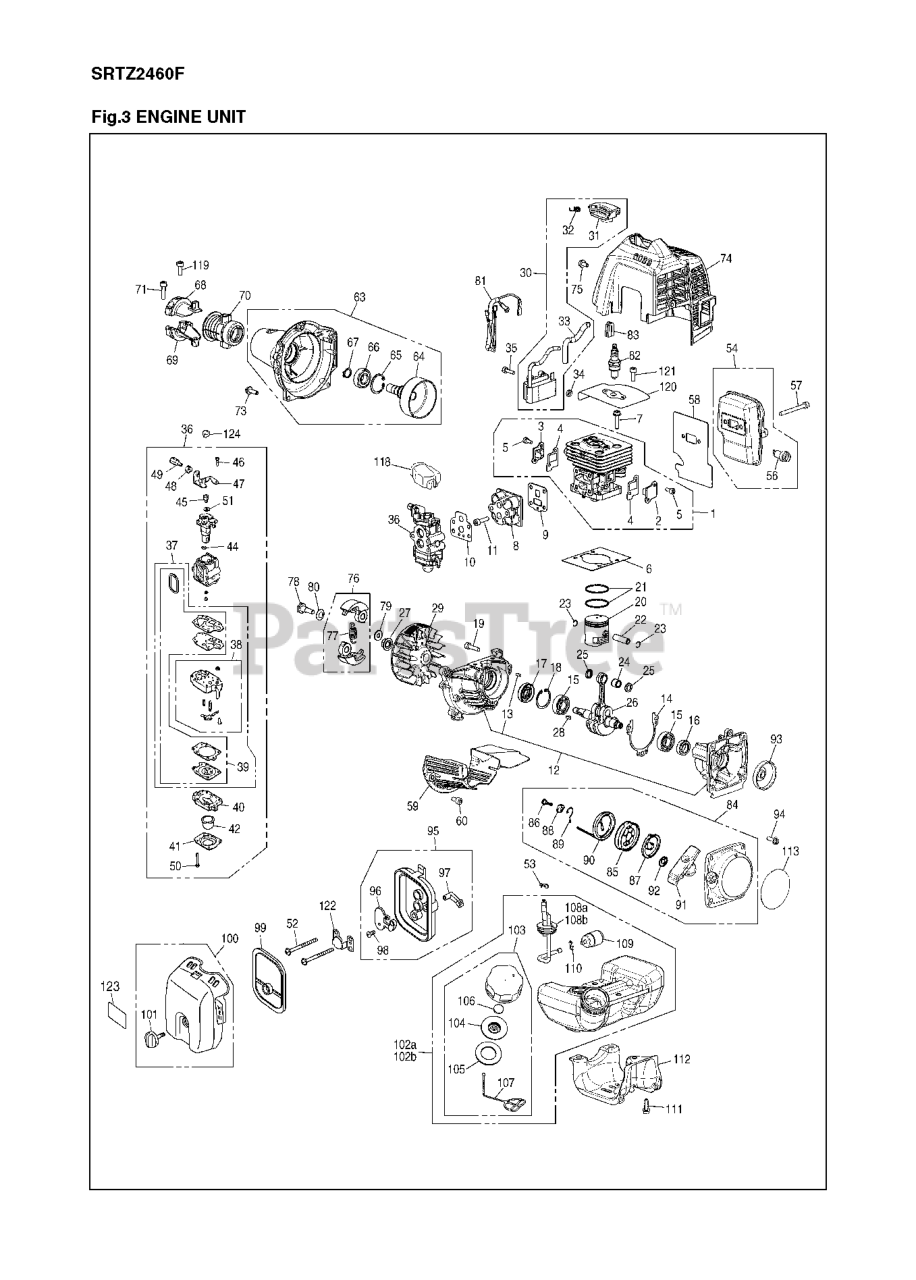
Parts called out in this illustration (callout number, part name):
1	CYLINDER COMP
2	COVER, TR-S
3	COVER, TR-F
4	GASKET, TR
5	BOLT
6	GASKET, BASE
7	BOLT
8	INSULATOR
9	INSULATOR GASKET(R-848F0814B0)
10	GASKET, CARB
11	BOLT TORX
12	CRANKCASE-C
13	PIN
14	GASKET, CASE
17	SEAL
22	PIN
26	CRANKSHAFT-C
27	NUT
28	KEY
30	COIL ASSY
34	SPACER
36	CARBURETOR ASSY
37	REBUILD KIT
38	CARBURETOR BODY
39	GASKET KIT
41	1OVER
44	RING
45	SWIVEL
46	SCREW
47	BRACKET
49	ADJUSTER
51	WASHER
52	BOLT TORX
53	CLIP
56	ARRESTER
58	GASKET, MUFFLER
63	COVER, C
64	DRUM (RPLS 481031120-22)
68	BRACKET (A) (RPLS T170031211)
69	BRACKET (B)
74	COVER, ENGINE
75	BOLT (RPLS T495051010-11)
76	SHOE COMP
81	CORD-COMP
82	SPARK PLUG CMR7H-10
84	RECOIL ASSY
87	SPRING, SPIRAL
88	COLLAR
89	SWING ARM
92	PLATE.STOPPER
95	CLEANER BODY ASSY
96	PLATE, CHOKE
98	SCREW
99	ELEMENT
100	COVER ASSY
101	Cleaner Knob
102	TANK ASSY
104	HOLDER-A
108	PIPE-C
108	PIPE ASSY
109	FILTER
110	CLIP
113	LABEL, RECOIL
